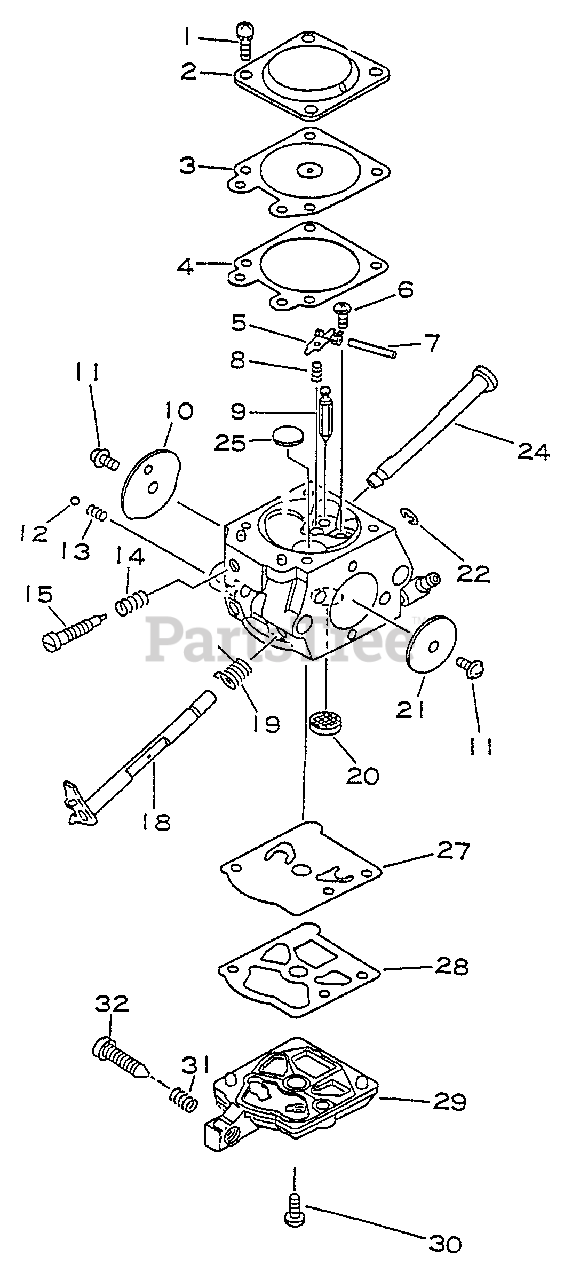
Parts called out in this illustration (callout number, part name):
1	SCREW
2	COVER, METERING
3	DIAPHRAGM, METERING
4	GASKET, METERING
5	LEVER, METERING
6	SCREW, METERING LEVER PIN
7	PIN, METERING LEVER
8	SPRING, METERING LEVER
9	VALVE, INLET NEEDLE
10	VALVE, CHOKE
12	BALL, CHOKE
15	NEEDLE - LOW SPEED
18	SHAFT, THROTTLE
19	SPRING, THROTTLE RETURN
20	STRAINER
21	VALVE, THROTTLE
22	RING, RETAINING
24	SHAFT, CHOKE
25	PLUG, WELCH
27	DIAPHRAGM, PURGE
28	GASKET, PURGE
29	COVER, PUMP
30	SCREW, PUMP COVER
31	SPRING, IDLE ADJUST
32	SCREW, IDLE ADJUST
